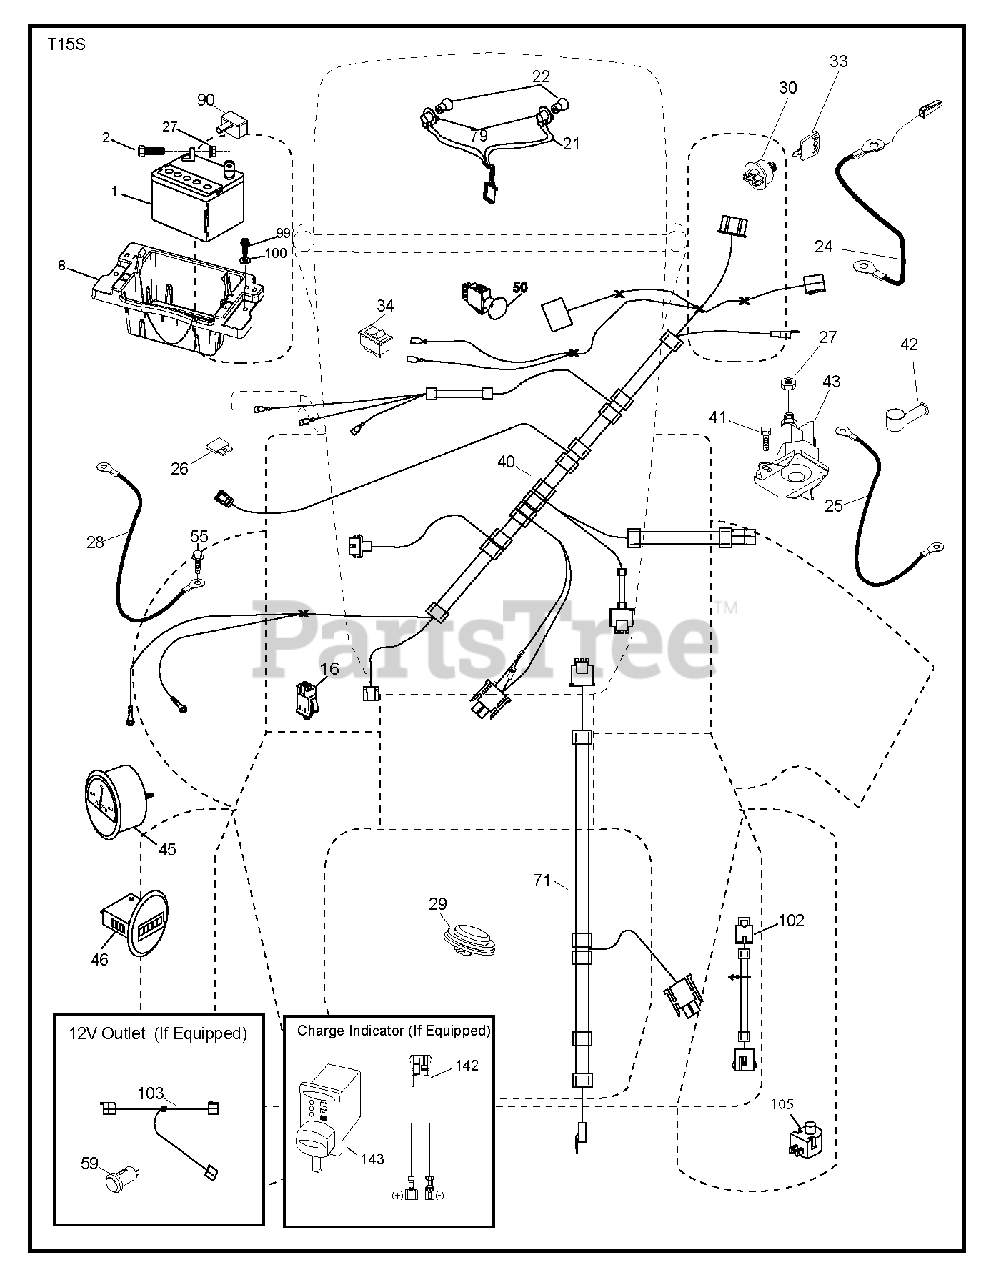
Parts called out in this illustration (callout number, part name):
1	REPL BY 532 12 38-99
2	BOLT.HEX.1/4.X.3/4.DICHROMATE
8	TRAY.BATTERY BOX.FRONT
16	SWITCH INTERLOOK PUSH-IN
21	HARNESS.LIGHT W/4152J BULBS
22	LIGHTBULB
24	Battery Cable with Wire, Front 8 Ga 8
25	Starter Cable, 8 Ga 17.5"
26	FUSE 20AMP
27	NUT
28	Ground Cable, 21" Black 8 Ga 90T
29	SWITCH.SEAT.DELTA.OPC.
30	SWITCH.IGN.DELTA.W.LGH.ROS
33	KEY.CHAIN.BLISTER.PACK.GEN.USA
34	SWITCH LT
40	HARNESS.IGN.DSH.W112V.WPORTWIR
41	SCREW
42	TERMINAL COVER
43	SOLENOID.W/BRASS.PLUNGER
45	AMMETER.ROUND.BLACK.DELTA
50	PTO Switch, 8-Terminal STD Black
55	SCREW 5/16"
71	HARNESS-CHASSIS SUB
79	BULB HOLDER ASM.
90	COVER.TERMINAL.BATTERY
99	SCREW HEXWSHR 1/4-20X3/4
102	HARNESS.PIGTAIL.VARIATOR.SD
105	REVERSE SWITCH
